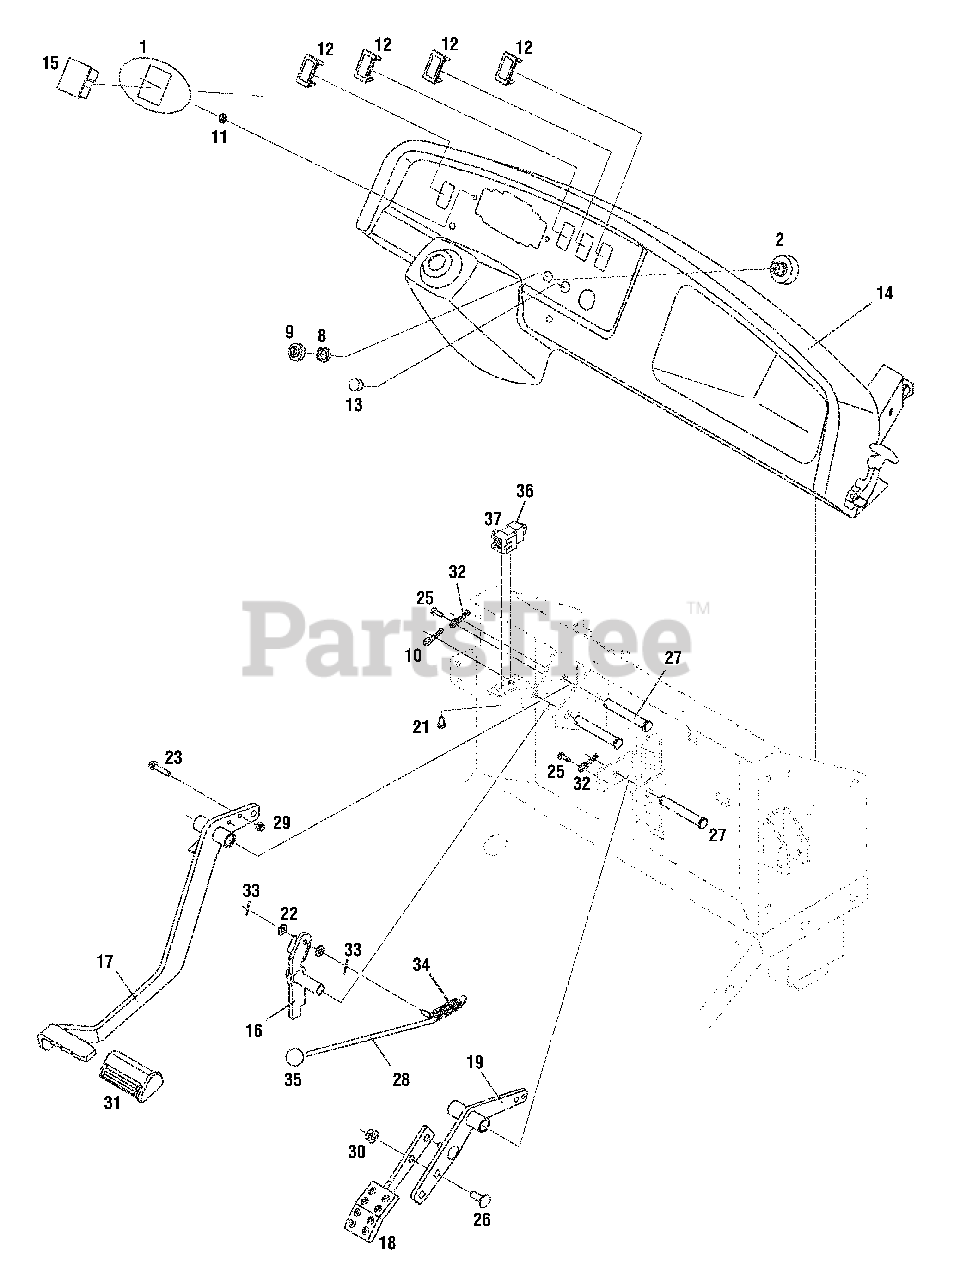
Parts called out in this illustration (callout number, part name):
1	Instrument Cover
2	Switch, Key
8	Nut, Ignition Switch, 5/8-32
9	Cap, Ignition Switch
10	Internal Cotter Pin
11	Nut, Retainer, 1/8
12	Switch Panel
13	Plug, Horn Switch
14	Dash Panel
15	Hour Meter
16	Lever, Parking Brake
17	Pedal Assembly, Brake
18	Pedal Assembly, Throttle
19	Pedal Arm Assembly, Throttle
21	Screw, Hi-Lo, 1/4-20 x .5
22	Washer, Flat .25 x .630 x .0515
23	Screw, Self-Tapping, 1/4-20x1.25
25	Screw, Self-tapping, #10-32 x.625
26	Bolt, Carriage, 3/8-16 x 1.0
27	Pin, Clevis.50 x 3.25
28	Rod, Brake Lock
29	Nut, Hexlock,` 1/4-20 GR 8
30	Nut, Flange Lock, 3/8-16
31	Pad, Brake Pedal
32	Pin, Cotter, 5/32 x 1.0 Lg.
33	Pin, Cotter, 1/16
34	Spring, Extension, .637 x 2.972
35	Knob, Ball
36	Cover, Protective
37	Snap Mount Switch, Interlock
